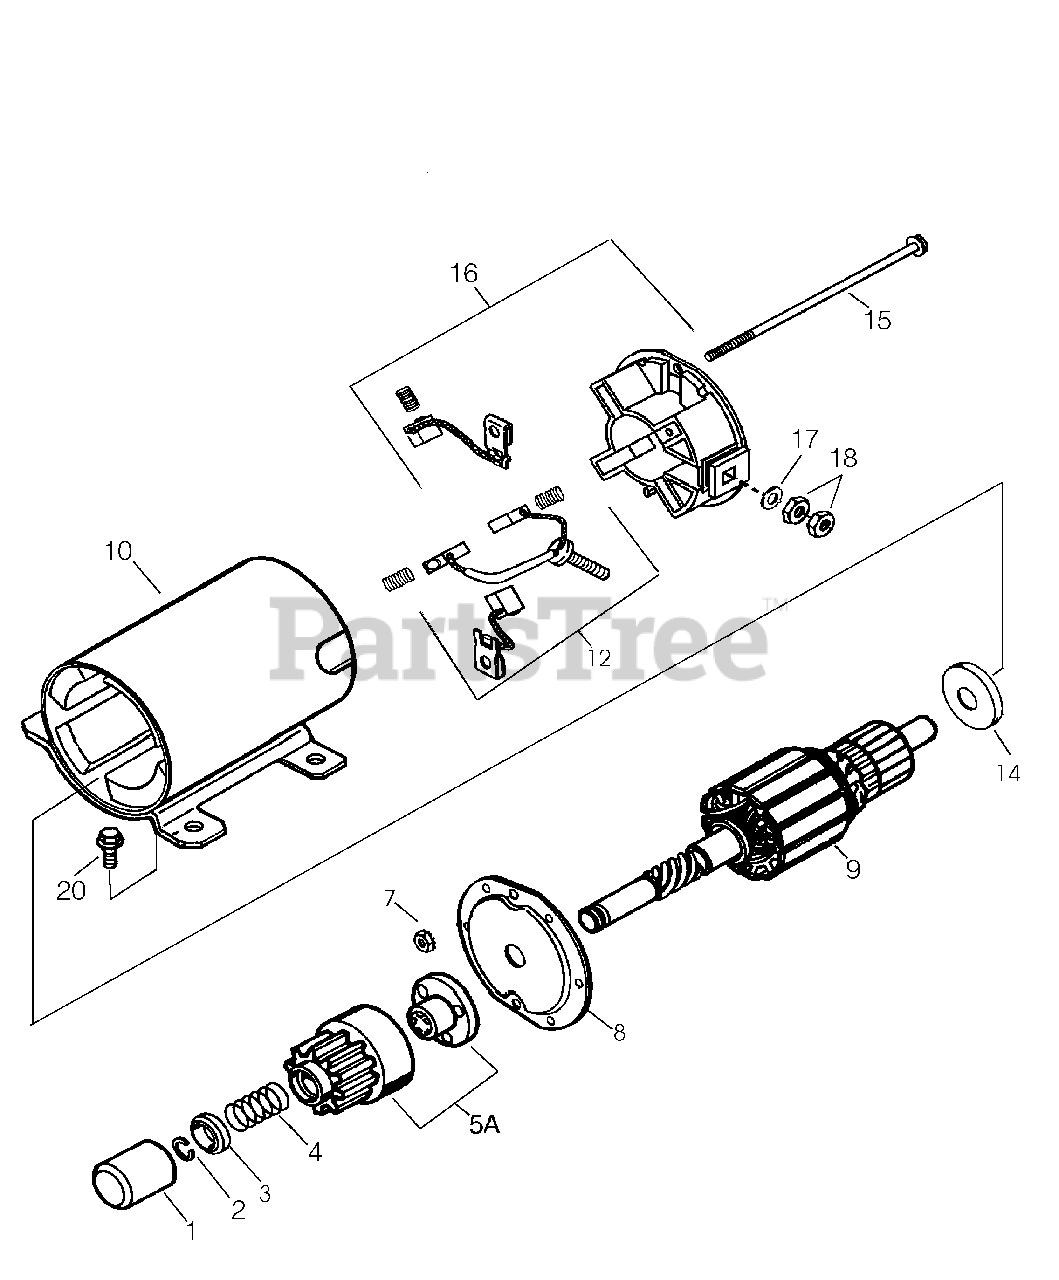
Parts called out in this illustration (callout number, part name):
1	Dust Cover
2	Retainer Ring
3	Spring Retainer
4	Anti-drift Spring
5A	Gear & Nut (Incl. 2)
7	Lock Nut
8	Drive End Cap Ass'y.
9	Armature
10	Housing Ass'y.
12	Brush & Spring Kit
14	Thrust Washer
15	Bolt, 10-32 X 4-11/64"
16	End Cap & Brush Card Ass'y. Incl. 12, 14,17,18
20	Screw, Torx T-30, 1/4-20 x 15/32"
